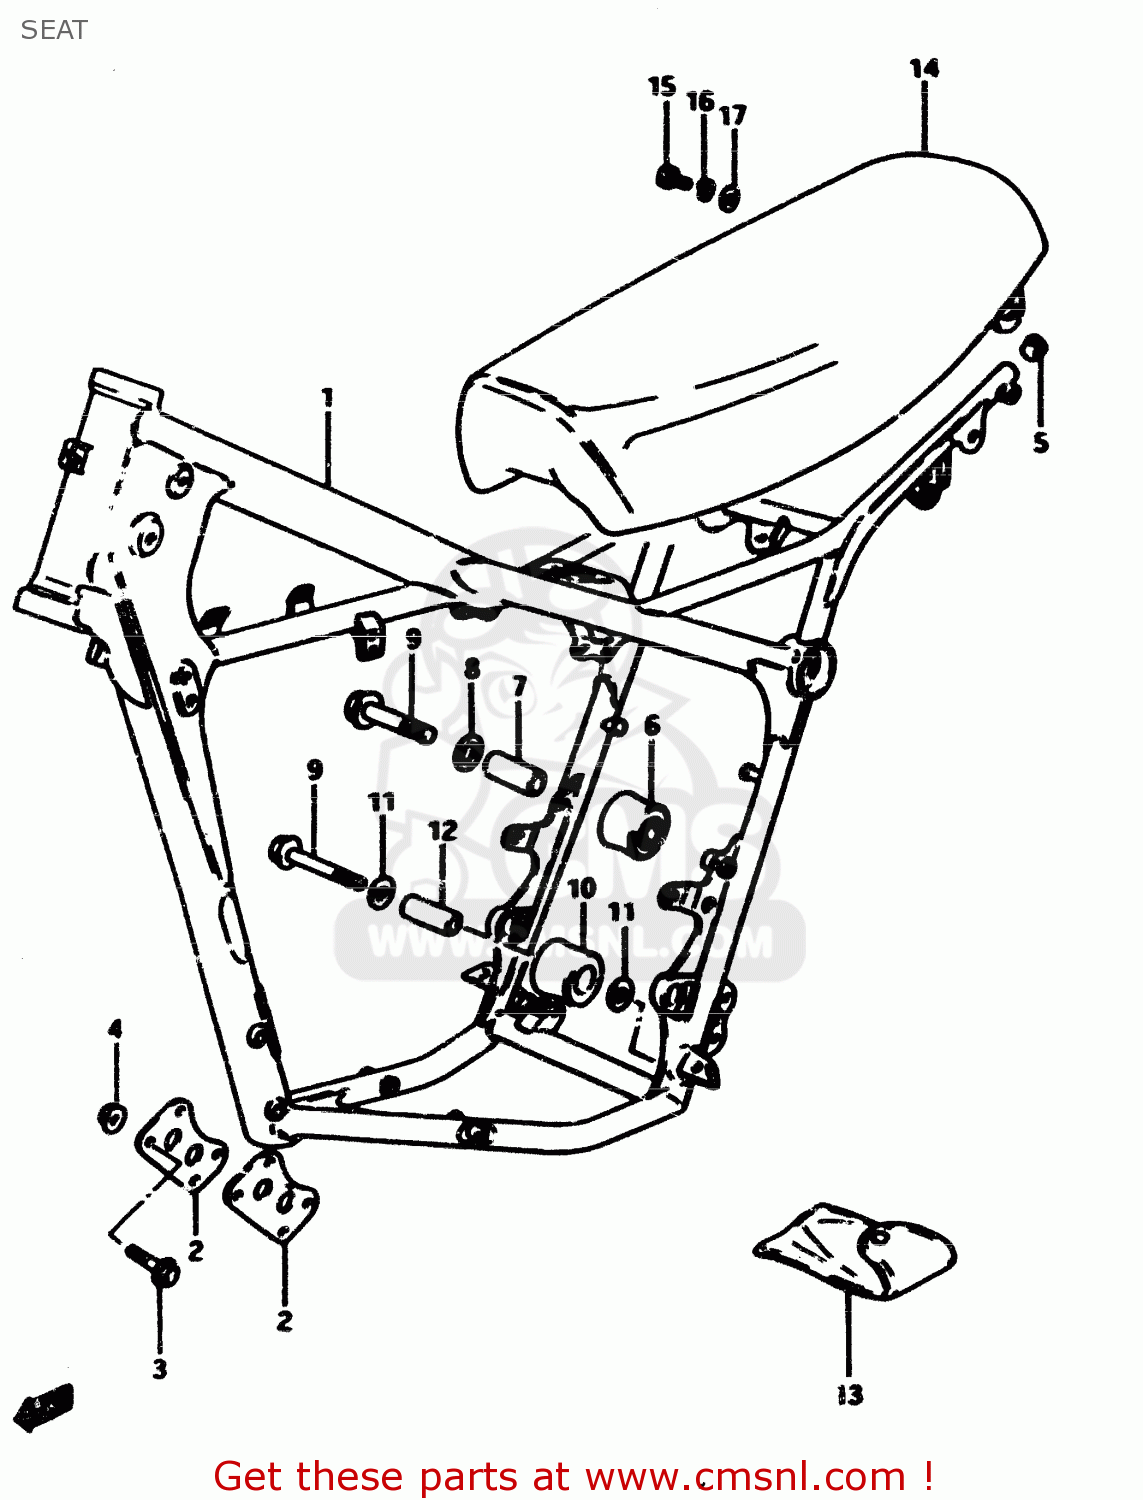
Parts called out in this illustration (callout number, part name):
1	FRAME
2	PLATE,ENGINE MOUNTING
3	BOLT(8X75)
4	NUT
5	PLUG(OD:17)
6	ROLLER,CHAIN
7	SPACER,CHAIN LENGTH ROLLER
8	WASHER
9	BOLT(8X45)
10	ROLLER,CHAIN LENGTH CONTROL
11	WASHER
12	SPACER, LOWER
13	TOOL SET
14	SEAT ASSEMBLY
15	BOLT
16	LOCK WASHER
17	WASHER
